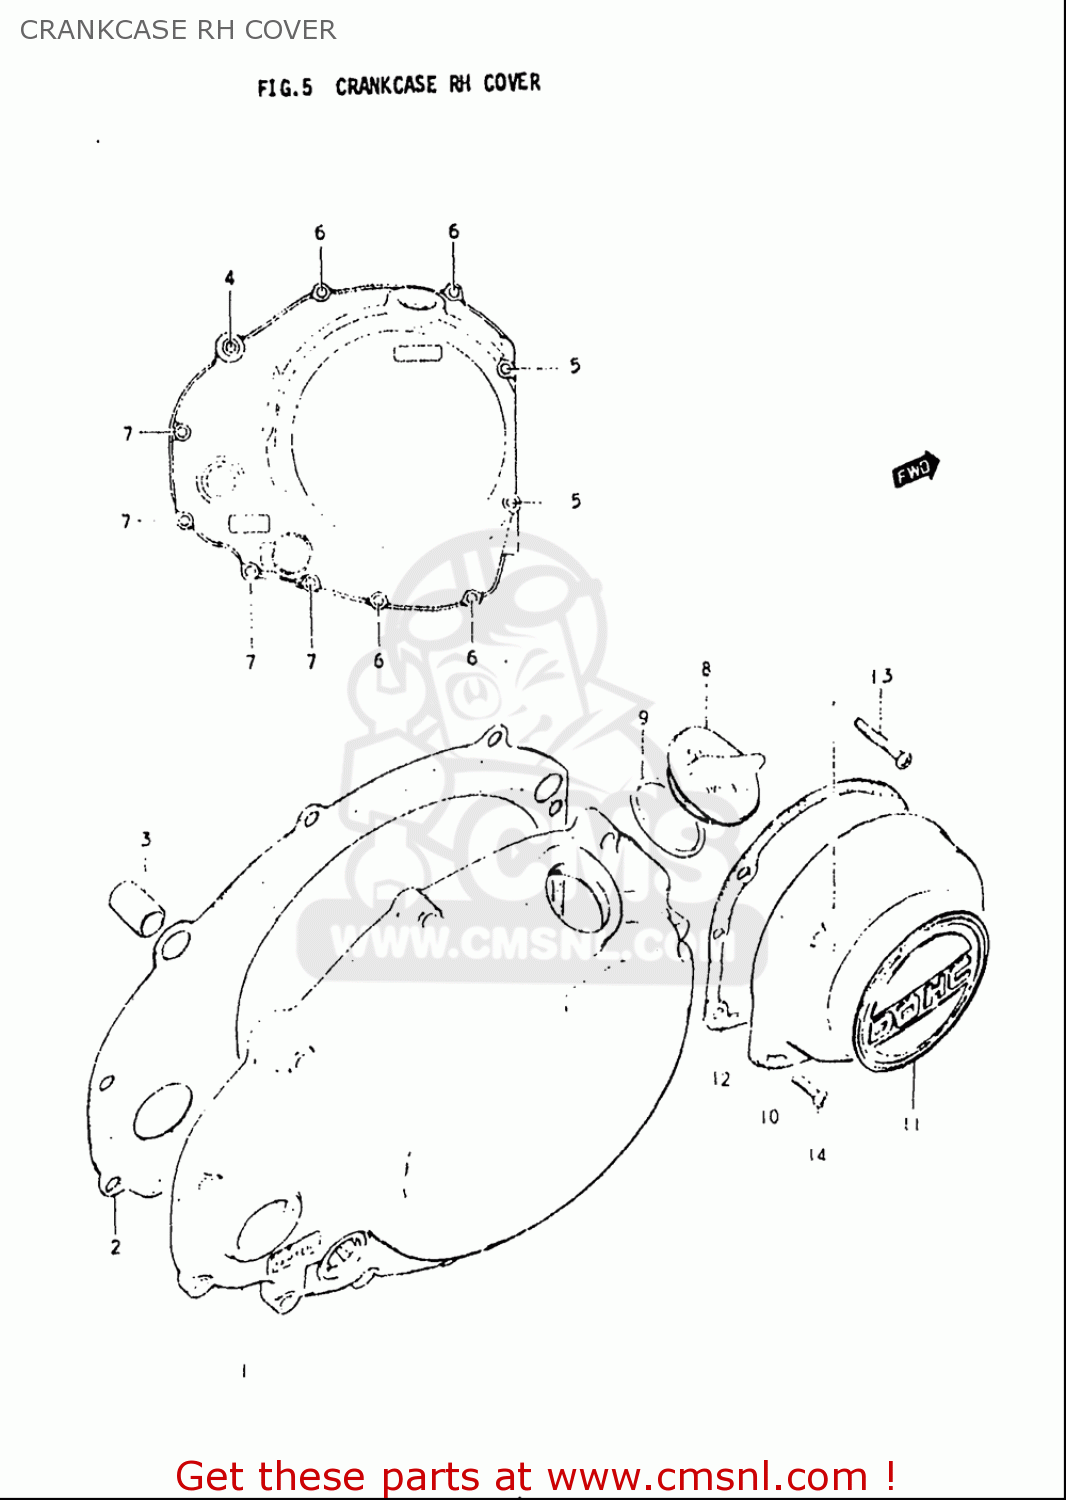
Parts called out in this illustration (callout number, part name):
2	GASKET,CLUTCH COVER (NAS)
3	PIN
4	SCREW
5	SCREW
6	SCREW
7	SCREW
8	PLUG SET
9	O RING(D:2.2,ID:32)
10	COVER,CONTACT BREAKER
11	EMBLEM,CONTACT BREAKER COVER
12	GASKET,CONTACT BREAKER COVER (NAS)
13	SCREW
14	SCREW
